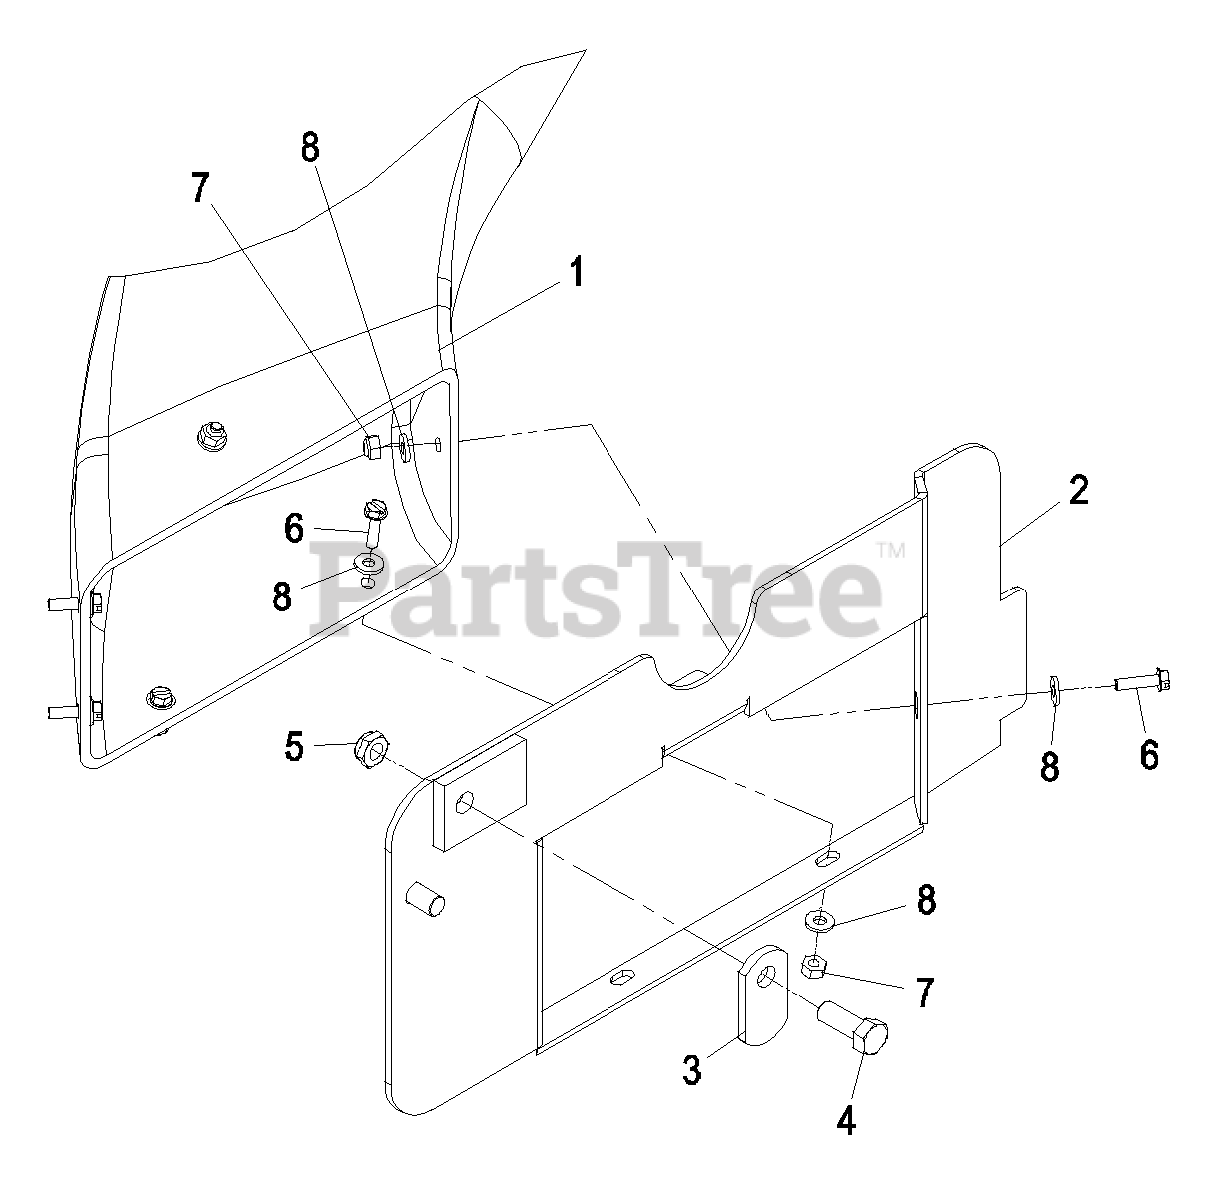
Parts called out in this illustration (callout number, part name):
1	BOOT,LOWER
2	BOOT FRAME ASM
3	LATCH-CATCHER, GRASS
4	SCREW-HH
6	SCREW-HWH
7	NUT-LOCK, NI
8	WASHER-FLAT
